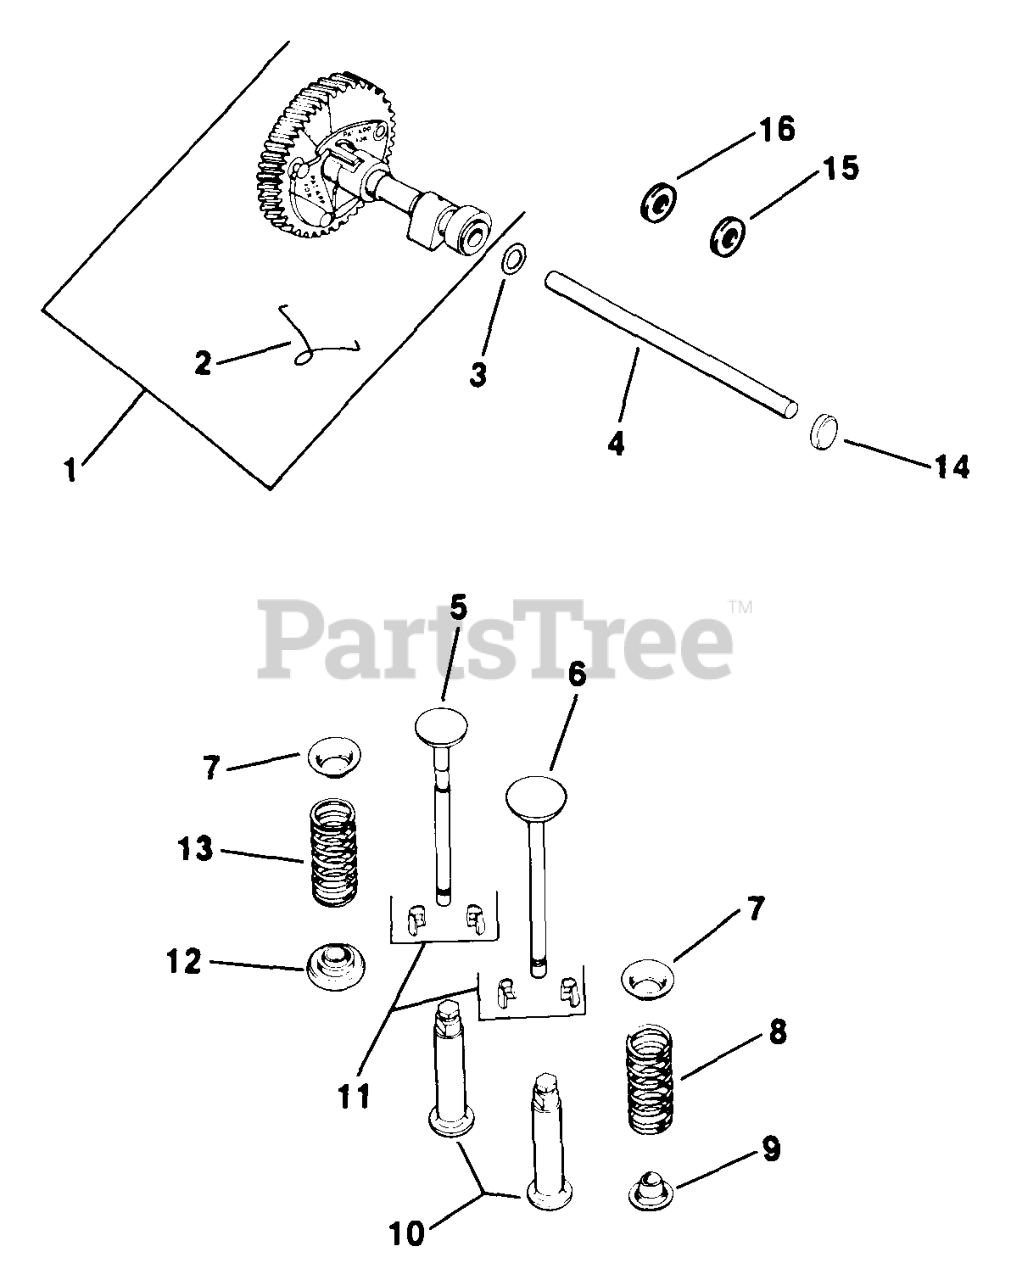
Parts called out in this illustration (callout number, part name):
1	CAMSHAFT ASSY - DISCONTINUED
2	SPRING, ACTUATING-DISCONTINUED
3	SPACER (.005")
3	SPACER (.010")
4	PIN, CAMSHAFT - DISCONTINUED
5	VALVE, EXHAUST
6	VALVE, INTAKE - DISCONTINUED
7	RETAINER, SPRING
8	SPRING, INTAKE VALVE - DISCONTINUED
9	RETAINER, VALVE SPRING
11	KIT, RETAINER
12	ROTATOR - USE 52 413 01
13	SPRING, EXHAUST VALVE-(#DSC)
14	PLUG, CUP 1/2" USE 25 139 50-S
15	WASHER, FLAT 7/32" - DISCONTINUED
16	WASHER, FLAT 3/16"
